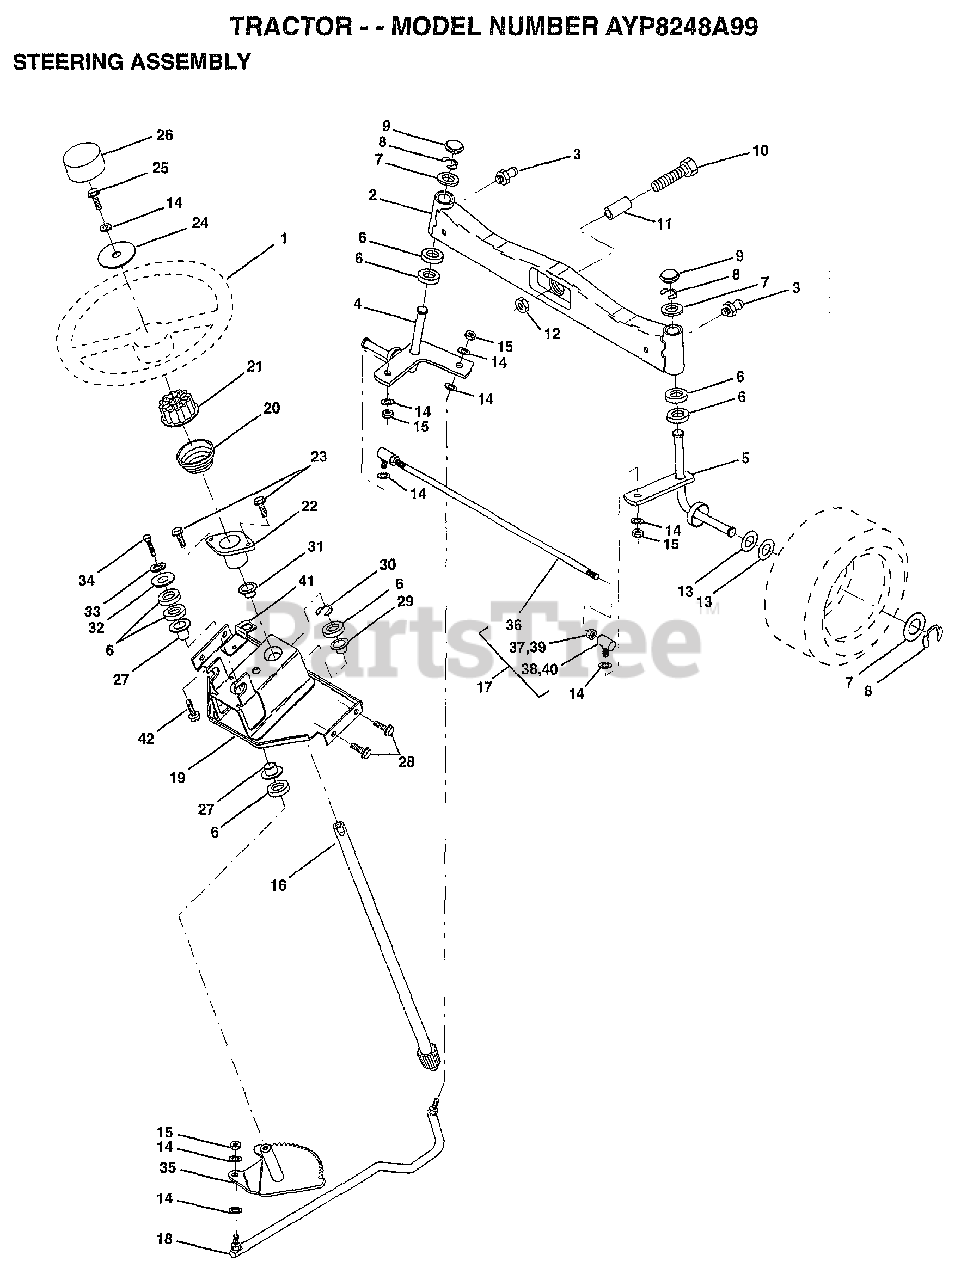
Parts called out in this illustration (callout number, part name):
3	ZERK M
4	SPINDLE ASM LH
5	SPINDLE ASM RH
6	WASHER .T
7	WASHER
8	RING
9	CAP
10	BOLT
11	SPACER BEARING
12	"NUT-LOC,FLANGE LT"
13	WASHER
14	LOCKWASHER
15	GRIPCO NUT
16	SHAFT.STEER.VGT
17	ROD.ASM.TIE.BALL
18	DRAGLINK.BALL.JOI
19	SUPPORT ASM-STEER
20	COLUMN.STEERING
21	ADAPTER LT
22	"BUSHING,STEERING"
23	"SCREW-TT,10-32 FL"
24	WASHER T
25	BOLT
26	"INSERT,STR WHEEL"
27	COL. SRTG. BEAR.
28	SCREW
29	"FLANGE GT, BEAR."
30	KLIP RING
31	BUSHING.NYLINER.
32	WASHER
33	LOCKWASHER
34	BOLT
35	GEAR.ASM.SECTOR.
37	NUT
38	JOINT.RH
39	NUT
40	JOINT.LH
41	"BRKT-SW, INTER"
42	SCREW LT
